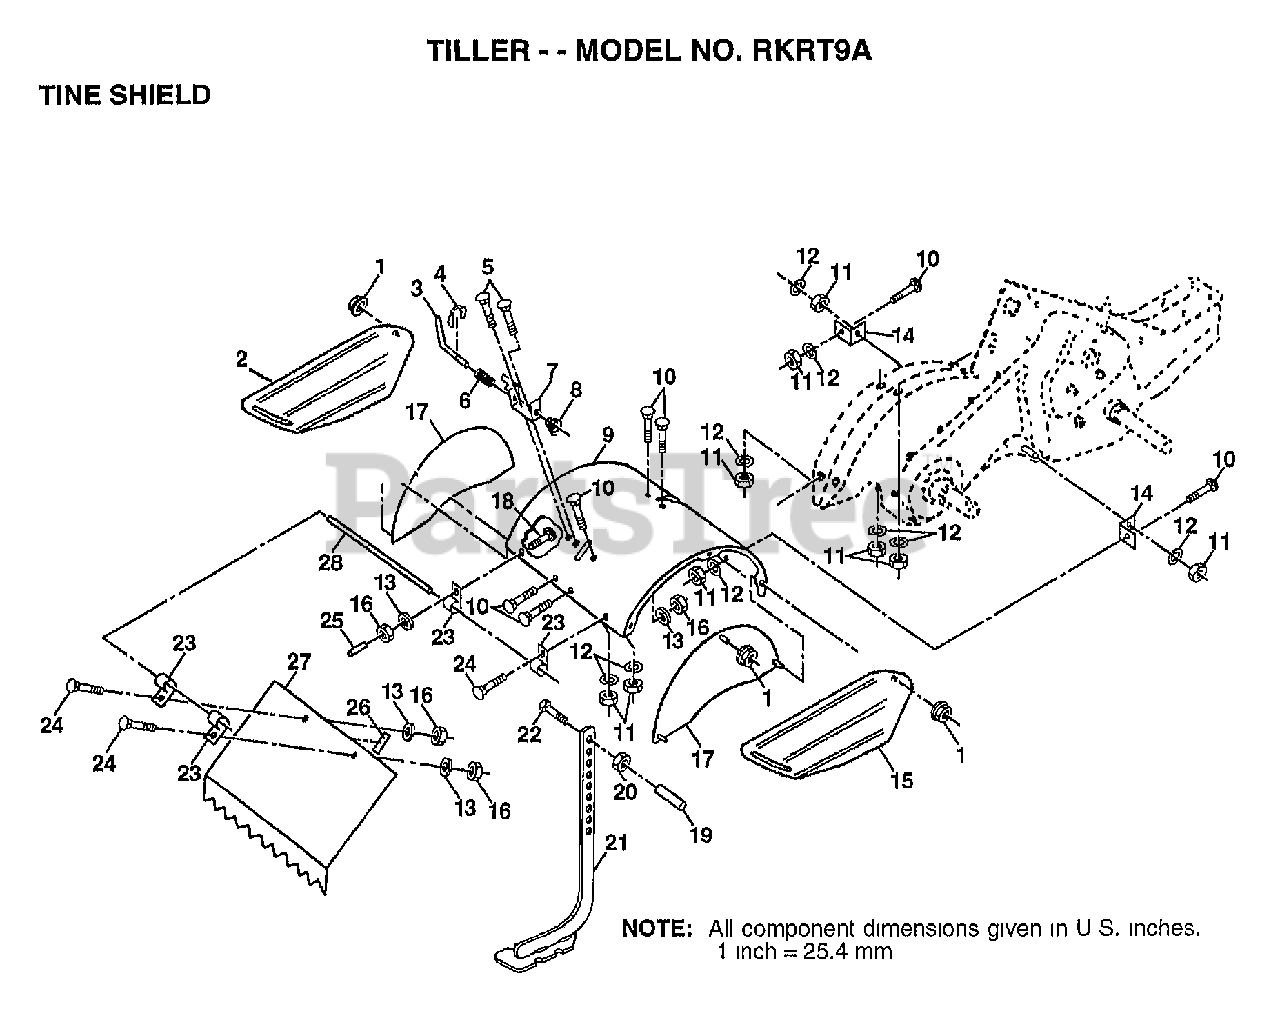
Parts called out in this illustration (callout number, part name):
1	NUT
2	SHIELD.SIDE.OUTER.LH
3	STAKE PIN TI
4	KLIP RING TI
5	BOLT
6	SPRING TI
7	LATCH BRACKET TI
8	SPRING CRT
9	SHIELD TINE
10	BOLT
11	NUT.HEX.5/16-18
12	LOCKWASHER
13	LOCKWASHER
14	TINE SHLD BRKT TI
15	SHIELD.SIDE.OUTER.RH
18	BOLT
19	GRIP CRT
20	NUT.HEX.3/8-16UNC
21	STAKE.ASM.DEPTH
22	BOLT
23	HINGE CRT
24	BOLT.1/4-20X1/2
25	VINYL CAP TI
26	PAD IDLER TI
27	SHIELD LEVELING
28	PIN.HINGE
